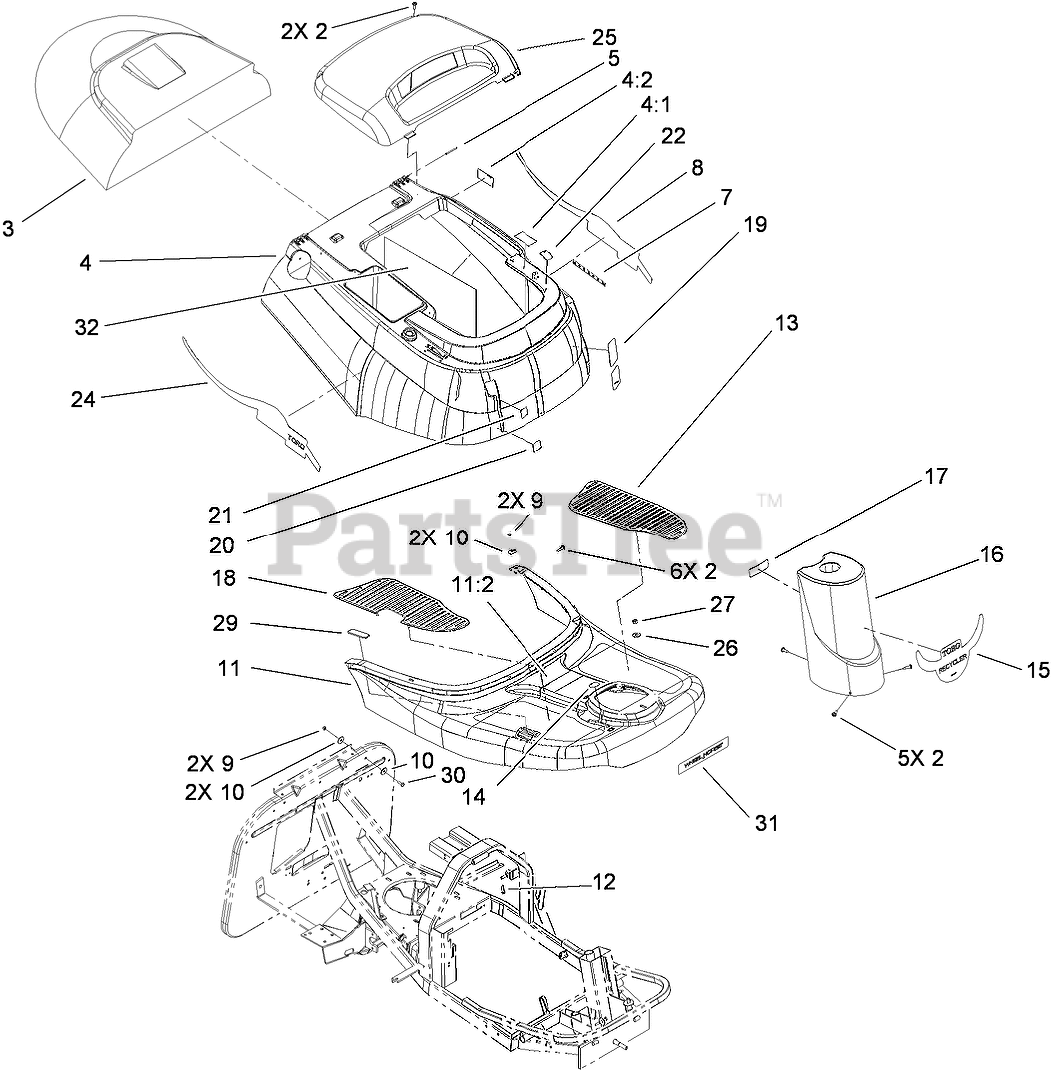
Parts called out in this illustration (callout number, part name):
2	Screw-HH, TAP
3	COVER-GRASS BAG
4	Shroud And Decal ASM
4:1	Decal-Danger
4:2	Decal-Warning, Hot
5	Pin-Dowel
7	Decal-Shift
9	NUT-LOCK
10	Washer-Flat
11	FOOT REST AND DECAL ASM
11:2	Decal-Caution
12	SCREW-HH
13	Floormat-LH
14	DECAL-CLUTCH, INTL RER
15	DECAL-FRONT
16	Steering-Turret
17	Decal-Run Lights
18	Floormat-RH
19	Decal-HOC
20	Decal-PTO, Disengage
21	Decal-PTO, Engage
22	Decal-Switch
25	Cover-Engine
26	Washer-Flat
27	NUT-LOCK
30	SCREW-HH
32	INSULATION
